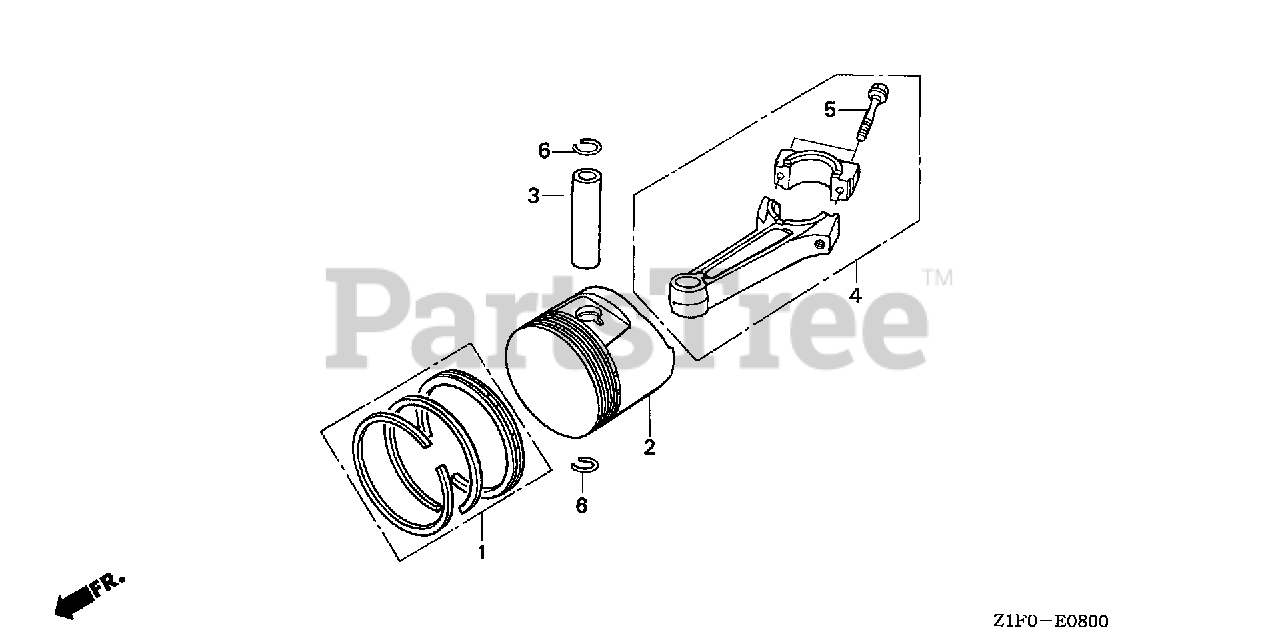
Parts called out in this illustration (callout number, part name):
1	RING SET, PISTON (STD) (RIKEN)
1	RING SET, PISTON (STD) (TPR)
1	RING SET, PISTON (0.25) (RIKEN)
1	RING SET, PISTON (0.25) (TPR)
1	RING SET, PISTON (0.50) (RIKEN)
1	RING SET, PISTON (0.50) (TPR)
1	RING SET, PISTON (0.75) (RIKEN)
1	RING SET, PISTON (0.75) (TPR)
2	PISTON (STD)
2	PISTON (OS 0.25)
2	PISTON (0.25)
2	PISTON (OS 0.50)
2	PISTON (0.50)
2	PISTON (OS 0.75)
2	PISTON (0.75)
3	PIN, PISTON
4	ROD ASSY., CONNECTING (STD)
4	ROD ASSY., CONNECTING (0.25 LOWER SIZE)
5	BOLT, CONNECTING ROD
6	CLIP, PISTON PIN (20MM)
